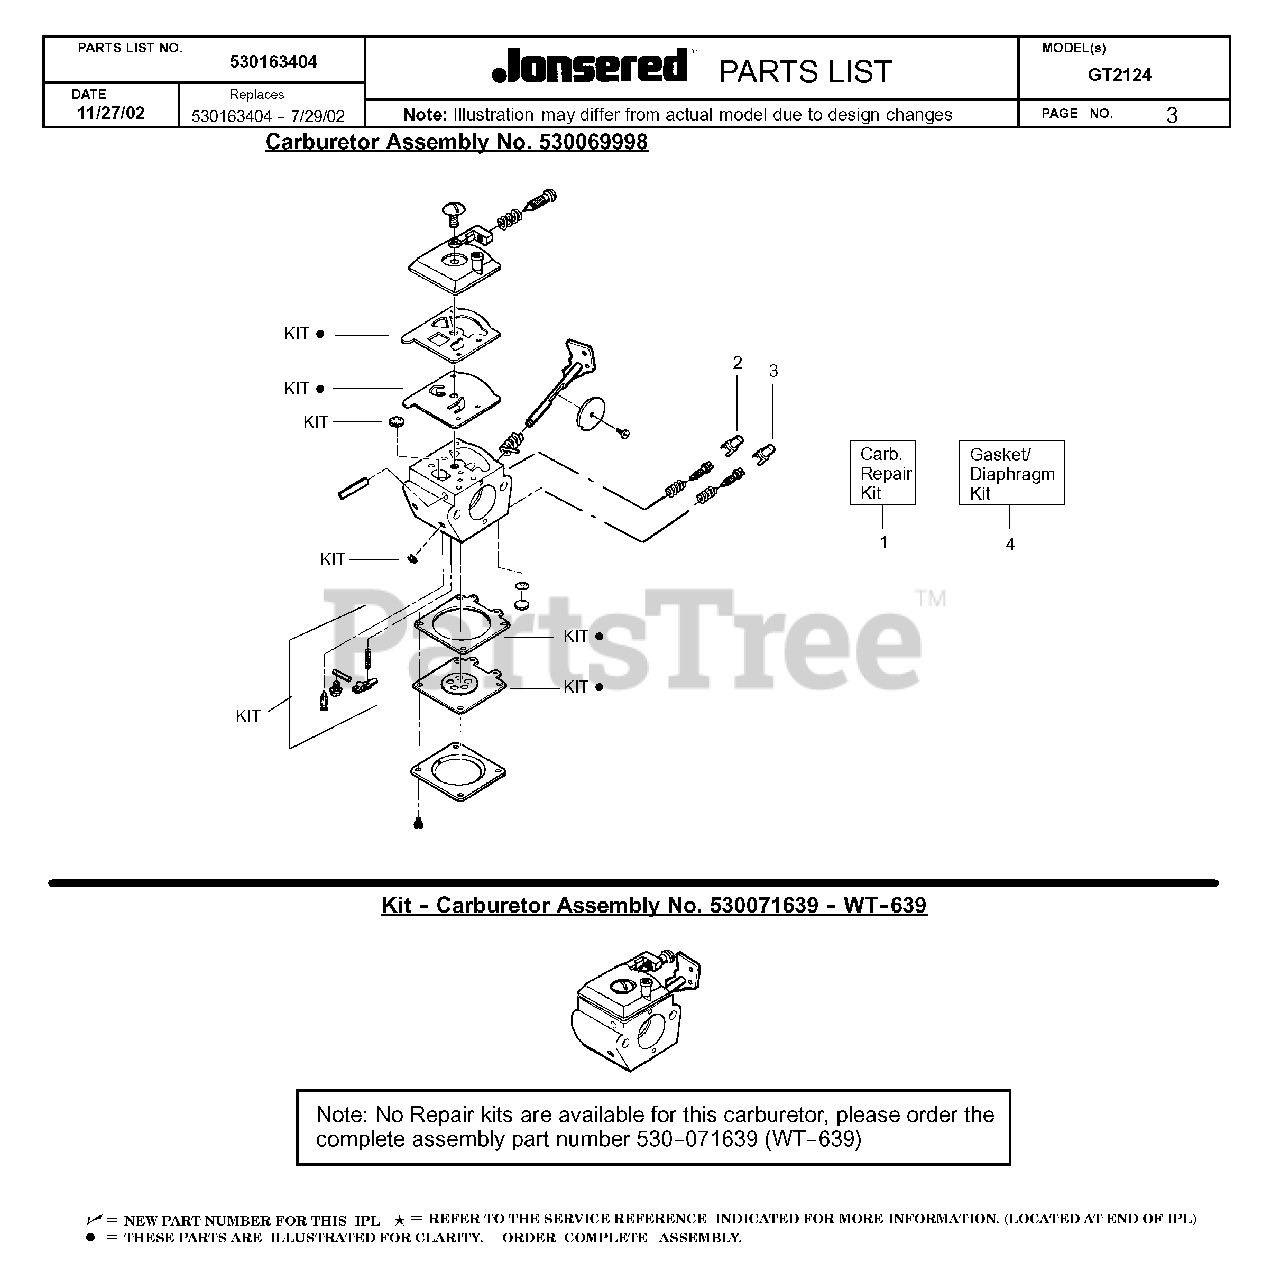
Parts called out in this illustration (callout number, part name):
1	CARB REPAIR KIT
2	LIMITER CAP-HIGH
3	LIMITER CAP-LOW
4	GASKET/DIAPHRAGM KIT
